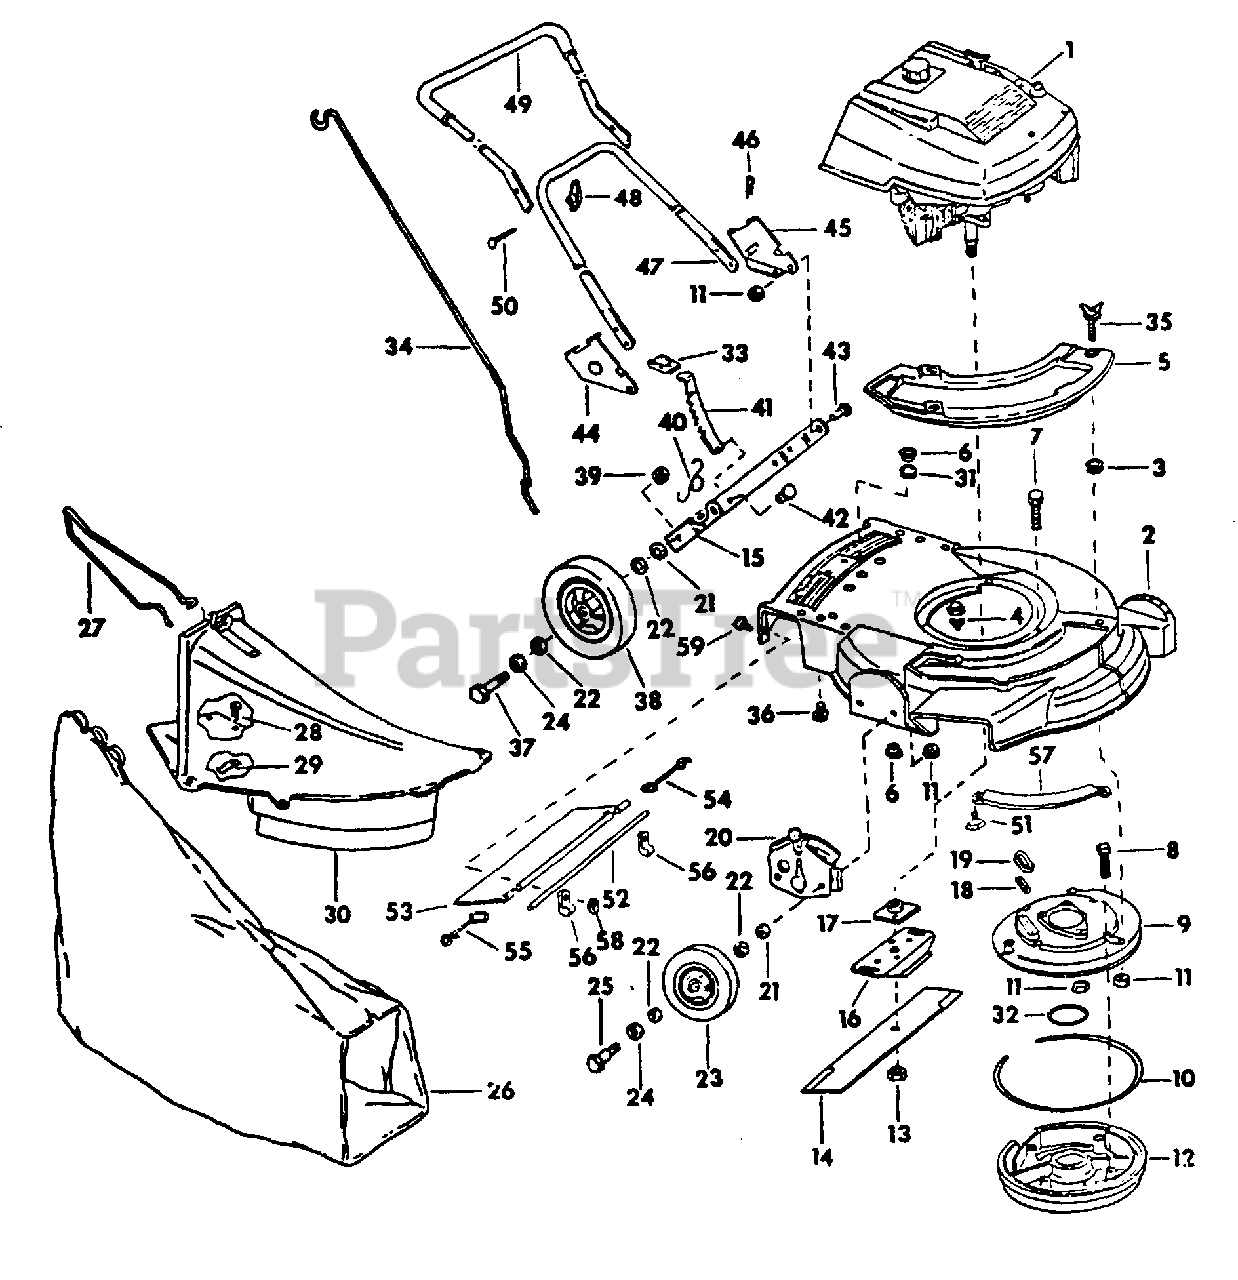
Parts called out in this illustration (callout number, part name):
1	ENGINE, IH
2	HOUSING ASSY, 21 IN.
4	SCREW, SHOULDER
5	COVER, CHUTE OPENING
6	SPACER, FLANGED
7	SCREW, MUFFLER PLT TO HSG
8	SCREW, MUFFLER TO PLATE
9	PLATE, MUFFLER
10	GASKET, MUFFLER OUTSIDE
12	COVER, MUFFLER
16	STIFFENER, BLADE
17	COLLAR & PLATE
18	GASKET, EXHAUST
19	SLEEVE, EXHAUST GASKET
20	ADJUSTMENT, HEIGHT
22	WASHER, FELT
23	WHEEL AND TIRE
24	WASHER, WHEEL BOLT HD
25	BOLT, WHEEL FRT SHOULDER
27	GUARD, WHEEL
30	CHUTE ASSY
32	GASKET, MUFFLER INSIDE
34	ROD, GRASS BAG
35	SCREW, WING
36	SCREW, HANDLE BRACKET
37	BOLT, REAR WHEEL
38	WHEEL & TIRE - 8 IN. REAR
39	NUT, REAR WHEEL BOLT
40	SPRING, HEIGHT ADJ
41	LEVER, REAR HGT ADJ
42	PIN, HEIGHT ADJ LEVER
44	BRACKET 6 PIN, RH
45	BRACKET 5 PIN, LH
47	HANDLE, BOTTOM
49	HANDLE & GRIP, TOP
54	SPRING, SHIELD LH
55	SPRING, SHIELD RH
57	BAR, TOE - 21 IN.
58	SCREW, 1/4-20 X 5/8 ZND HEX-HD CAP
59	NUT, 1/4-20 HEX LOCK CAD.
